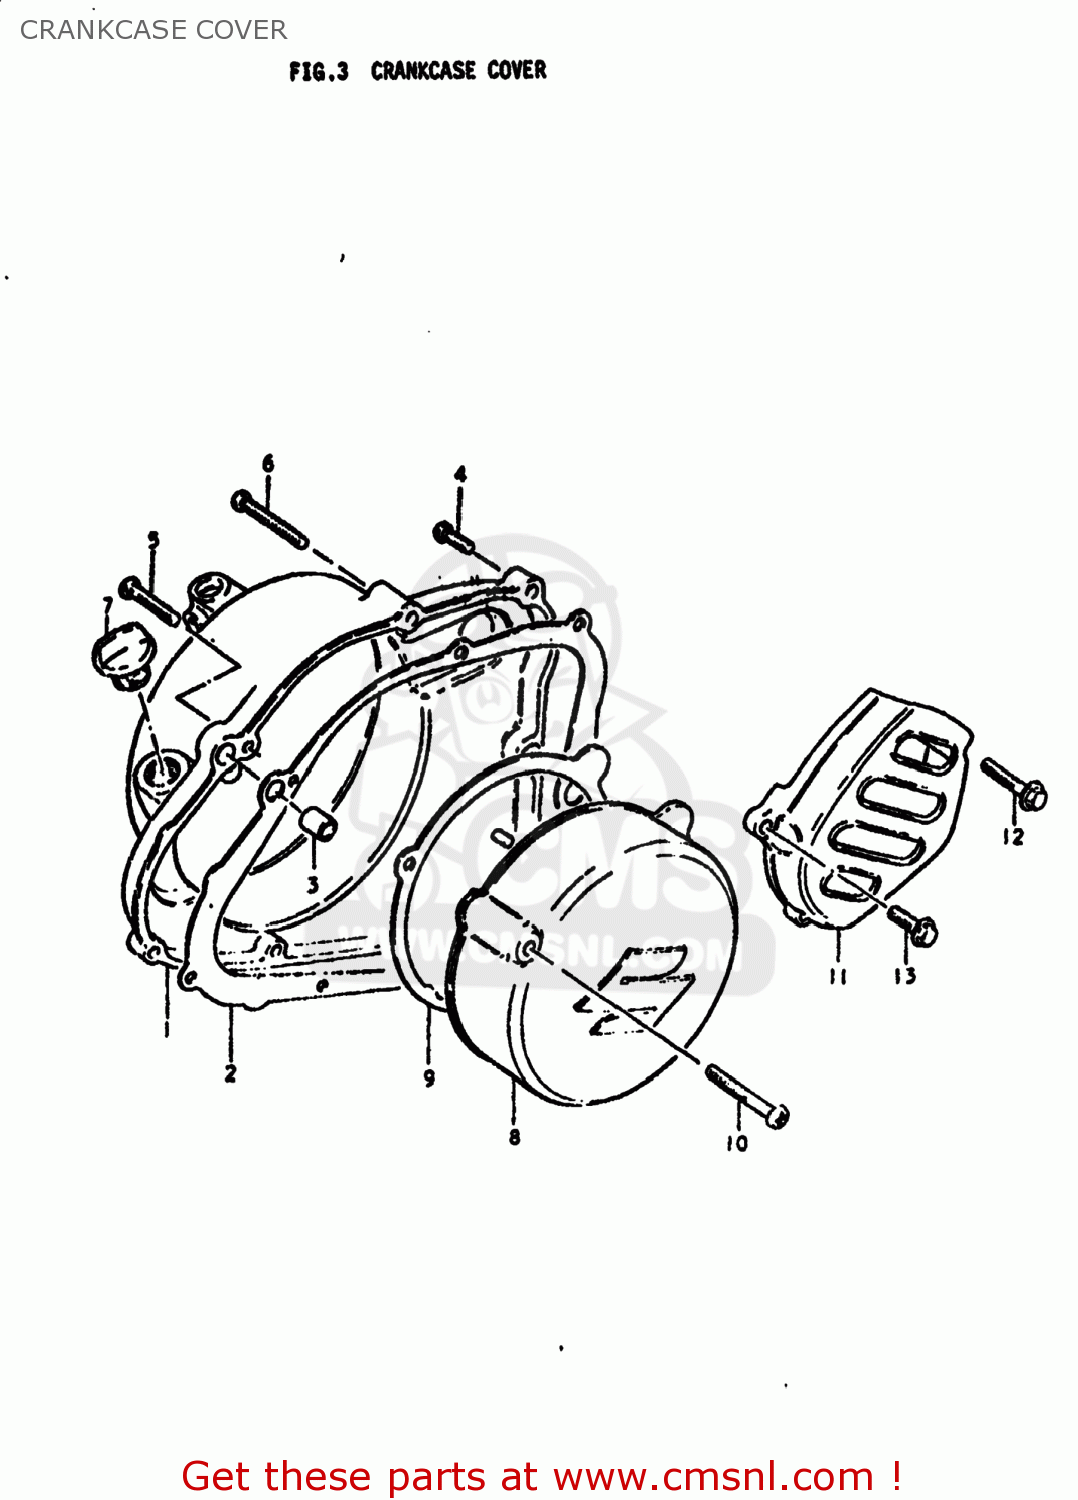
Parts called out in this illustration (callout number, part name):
1	COVER,CLUTCH
2	GASKET,CLUTCH COVER (AS (MCA)
3	PIN
4	SCREW
5	SCREW
6	SCREW (6X45)
7	PLUG,OIL FILTER
8	COVER
9	GASKET,MAGNETO COVER (NAS)
10	SCREW
11	COVER,ENGINE SPROCKET
12	BOLT,UNDER
13	BOLT
